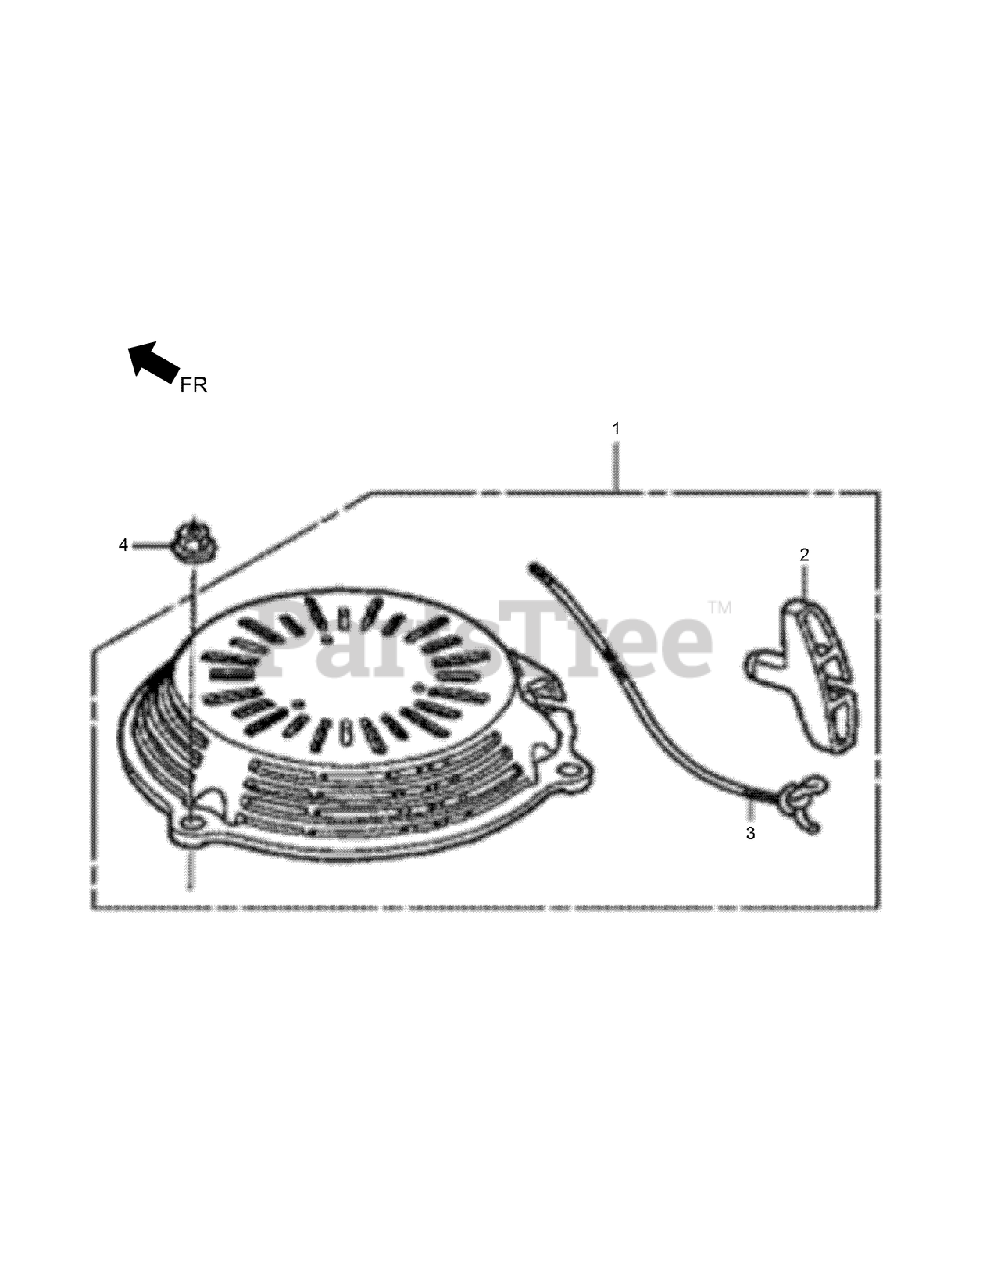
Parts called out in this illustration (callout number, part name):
1	STARTER ASM-RECOIL (NH1)
2	GRIP-STARTER
3	ROPE-RECOIL STARTER
4	NUT-FLANGE-6MM
